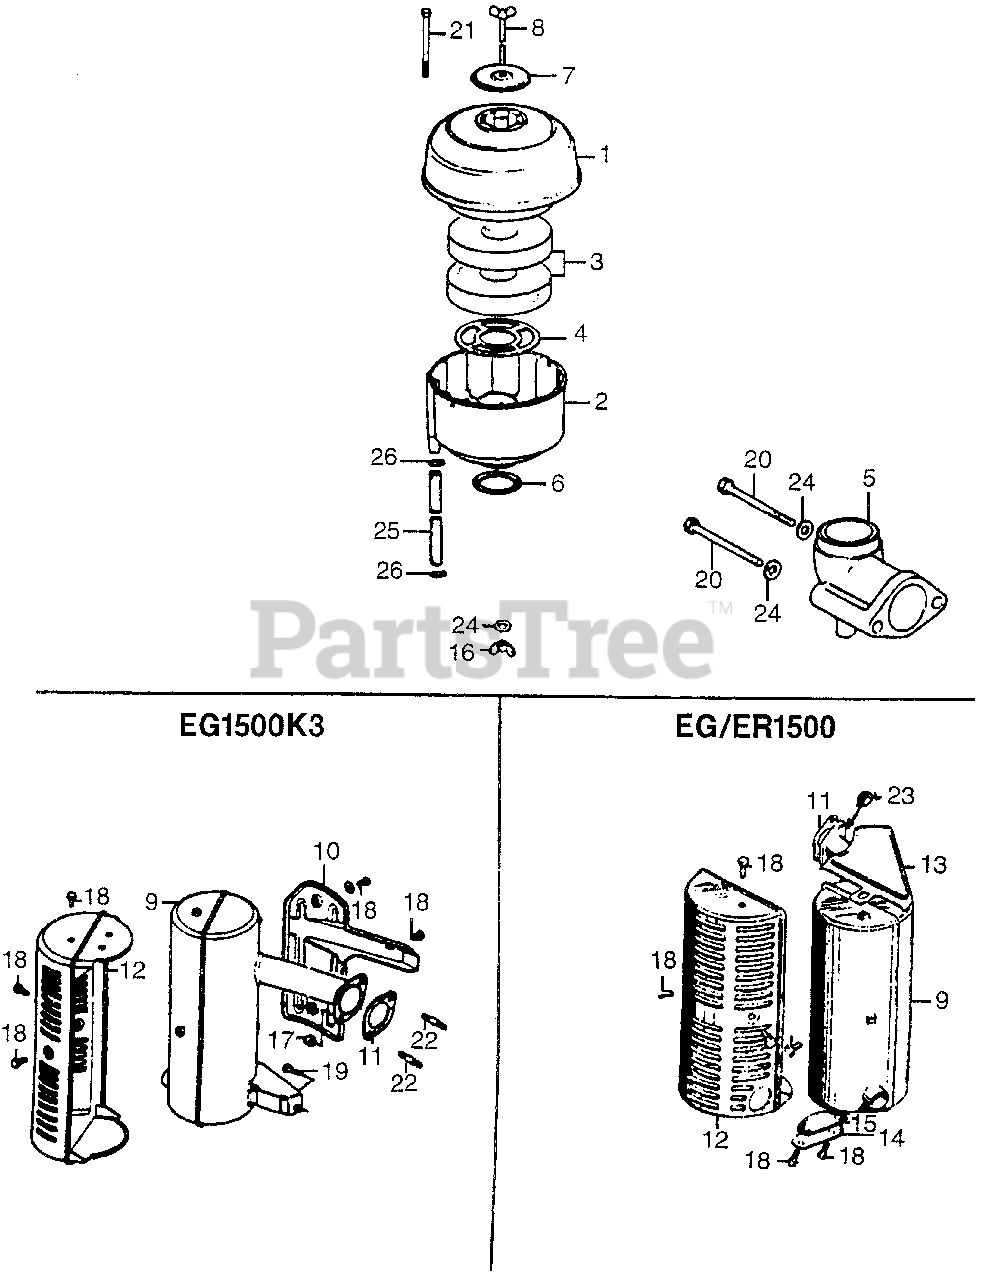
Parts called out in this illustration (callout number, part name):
1	BODY, CLEANER *NH31* (MCKINLEY WHITE) (NOT AVAILABLE)
2	PAN, AIR CLEANER OIL
3	ELEMENT, AIR CLEANER
4	GRID, AIR CLEANER
5	ELBOW, AIR CLEANER (NOT AVAILABLE)
6	GASKET, IN. ELBOW (NOT AVAILABLE)
7	CAP, AIR CLEANER
9	MUFFLER (NOT AVAILABLE)
11	GASKET, MUFFLER (NOT AVAILABLE)
12	PROTECTOR, MUFFLER (NOT AVAILABLE)
13	COVER, EX. PIPE
14	LID, MUFFLER (NOT AVAILABLE)
15	GASKET, MUFFLER LID (NOT AVAILABLE)
16	WINGNUT, TOOL BOX SETTING
18	BOLT, HEX. (6X8)
20	BOLT, HEX. (6X40)
21	BOLT, HEX. (6X160)
23	NUT, HEX. (6MM)
24	WASHER, PLAIN (6MM)
25	BULK HOSE, FUEL (8X1000) (8X240)
25	TUBE (8X240)
26	CLIP, TUBE (B12.5)
